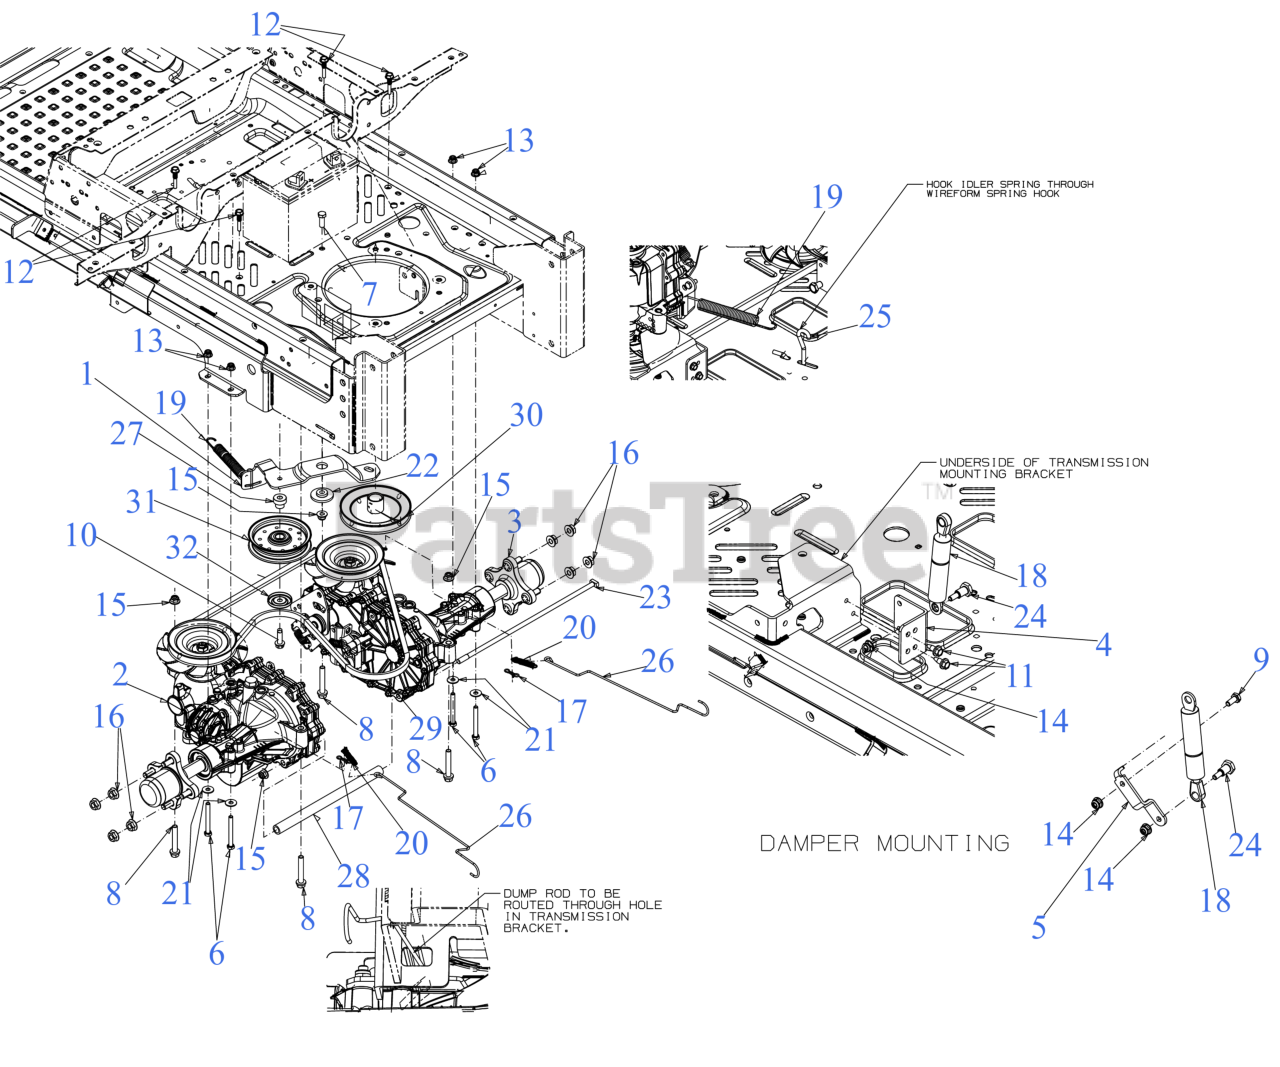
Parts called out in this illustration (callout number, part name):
1	IDLER BRACKET ASSEMBLY
2	TRANSMISSION (LH)
3	TRANSMISSION (RH)
6	HEX SCREW 5/16-18 x 2.75
7	SCREW 3/8-16 x 1 GR5
8	SCREW 3/8-16 x 2.25 GR5
9	SCREW 1/4-20 x .620 GR5
10	SCREW 3/8-16 X1.250
11	SCREW 1/4-20X.625
12	BELT KEEPER ROD .25 x 1.585
13	FLANGE LOCK NUT 5/16-18
14	FLANGE LOCK NUT
16	HEX FLANGE NUT 7/16-14
17	BOW TIE COTTER PIN 1/4-5/16
18	HYDRAULIC CYLINDER DAMPENER
19	EXTENTION SRING .75 DIA. x 6.85
20	EXTENSION SPRING .380 ODX 2.000 LG
21	FLAT WASHER
22	SHOULDER SPACER
23	SUPPORT TUBE ROD
24	SHOULDER BOLT .395 DIA x .56 LG
25	IDLER SPRING HOOK
27	SHOULDER SPACER
28	TRANSMISSION SPACER .75OD x 11.31
29	TRANSMISSION DRIVE BELT A x 67
30	TRANMISSION DRIVE PULLEY
31	IDLER PULLEY 4.25 DIA
32	IDLER PULLEY CAP
